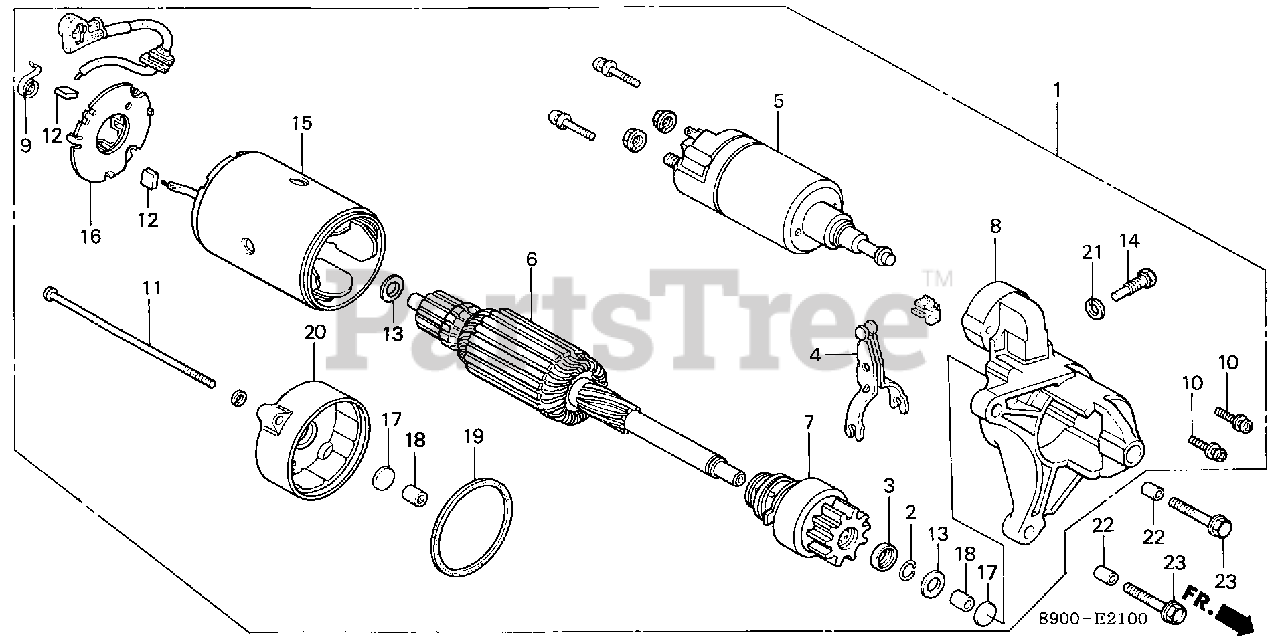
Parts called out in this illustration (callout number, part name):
1	STARTER MOTOR ASSY.
2	RING, SNAP (NOT AVAILABLE)
3	COLLAR, CLUTCH STOP
4	LEVER, PINION DRIVE (NOT AVAILABLE)
5	SWITCH, MAGNETIC
6	ARMATURE (NOT AVAILABLE)
7	PINION
8	CASE, GEAR
9	SPRING, BRUSH (NOT AVAILABLE)
10	SCREW, MAGNETIC SWITCH SETTING
11	BOLT, THROUGH
12	BRUSH (NOT AVAILABLE)
13	WASHER
14	SCREW, POLE CORE SETTING
15	COIL, FIELD
16	HOLDER, BRUSH
17	COVER, BEARING
18	BUSH, BEARING
19	GASKET, RUBBER PLATE
20	COVER, RR.
21	WASHER, SPRING (8MM)
22	PIN, DOWEL (10X16)
23	BOLT, FLANGE (8X35)
